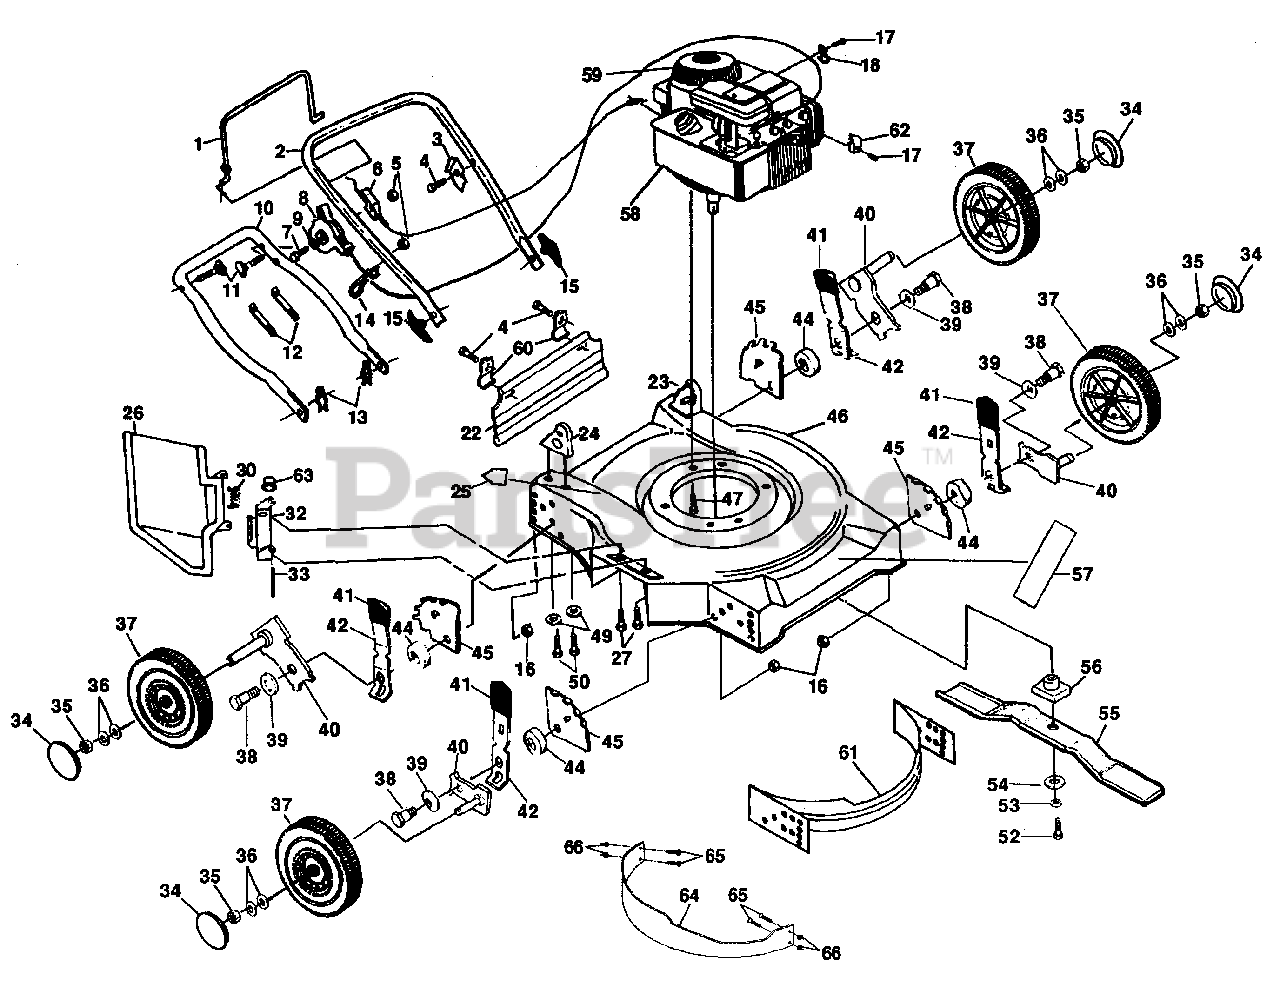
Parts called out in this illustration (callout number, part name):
1	Control Bar (AYP part number)
2	Upper Handle (AYP part number)
3	Up-Stop Bracket (AYP part number)
4	Hex Washer Head Screw #10-24 X 1/2 (AYP part number)
5	Locknut 1/4-20 (AYP part number)
6	Engine Zone Control Cable (AYP part number)
7	Flat Washer 9/32 x 5/8 x 1/16 (AYP part number)
8	Throttle Control
9	Machine Screw 1/4-20 x 2-1/8 (AYP part number)
10	Lower Handle (AYP part number)
11	Handle Bolt 5/16-18 x 1-3/4 (AYP part number)
12	Wire Tie (AYP part number)
13	Hairpin Cotter (AYP part number)
14	Rope Guide
15	Handle Knob (AYP part number)
16	Locknut 3/8-16 (AYP part number)
17	Thread Rolling Screw #10-32 x 5/8 (AYP part number)
18	Cable Clamp (Engine) (AYP part number)
22	Rear Skirt (AYP part number)
23	Handle Bracket Assembly (Left) (AYP part number)
24	Handle Bracket Assembly (Right) (AYP part number)
25	Danger Decal (AYP part number)
26	Discharge Guard
27	Hex Head Thread Rolling screww/Sems. 1/4-20 x 3/8 (AYP part number)
30	Torsion Spring (AYP part number)
32	Housing Bracket (AYP part number)
33	Hinge Rod (AYP part number)
34	Hubcap (AYP part number)
35	Locknut (AYP part number)
36	Washer (AYP part number)
37	Wheel Assembly
38	Shoulder Bolt 3/8-16 (AYP part number)
39	Belleville Washer 1/2 (AYP part number)
40	Axle Arm Assembly (AYP part number)
41	Selector Knob
42	Selector Spring (AYP part number)
44	Spacer (AYP part number)
45	Wheel Adjuster Bracket (AYP part number)
46	Lawn Mower Housing (Inc. Ref. #25)
47	Hex Head Thread Rolling Screw 3/8-16 x 1 (AYP part number)
49	Flat Washer 5/16 (AYP part number)
50	Thread Cutting Screw 5/16-18 x 3/4 (AYP part number)
52	Hex Head Screw 3/8-24 x 1-3/8, Grade 8
53	Helical Spring Washer 3/8 (AYP part number)
54	Hardened Washer (AYP part number)
55	22" Blade (AYP part number)
56	Blade Adapter (AYP part number)
57	Decal "Housing" (AYP part number)
59	Starter Guard
60	Skirt Bracket (AYP part number)
61	Front or Rear Baffle (AYP part number)
62	Throttle Clip (AYP part number)
63	Push On Speed Nut (AYP part number)
64	Baffle Mulcher (AYP part number)
65	Locknut (AYP part number)
66	Screw (AYP part number)
